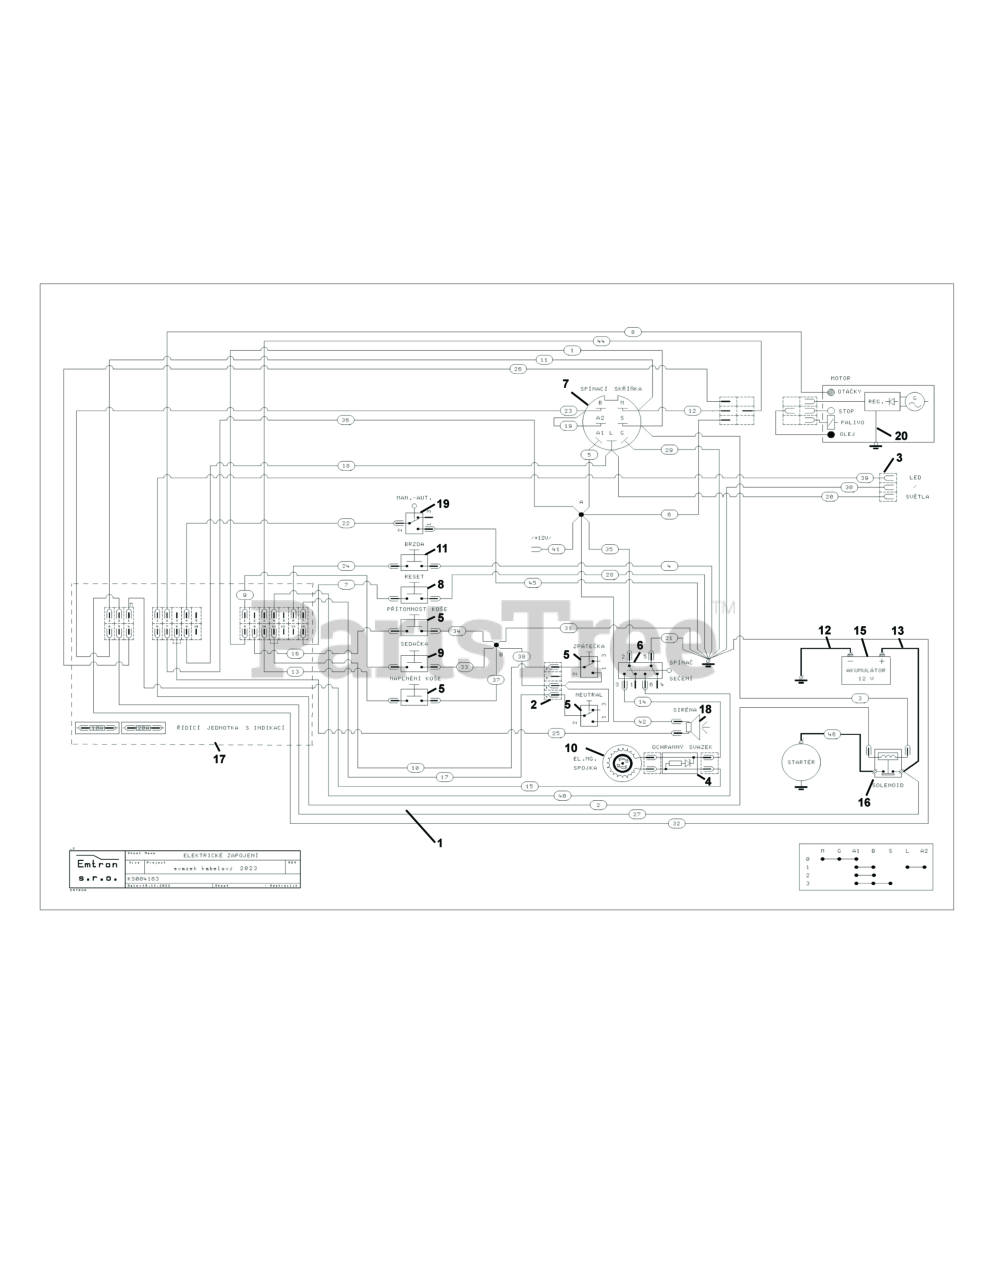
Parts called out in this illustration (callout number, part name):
1	HARNESS, Wiring
3	CONNECTOR
5	MICROSWITCH
16	SOLENOID
